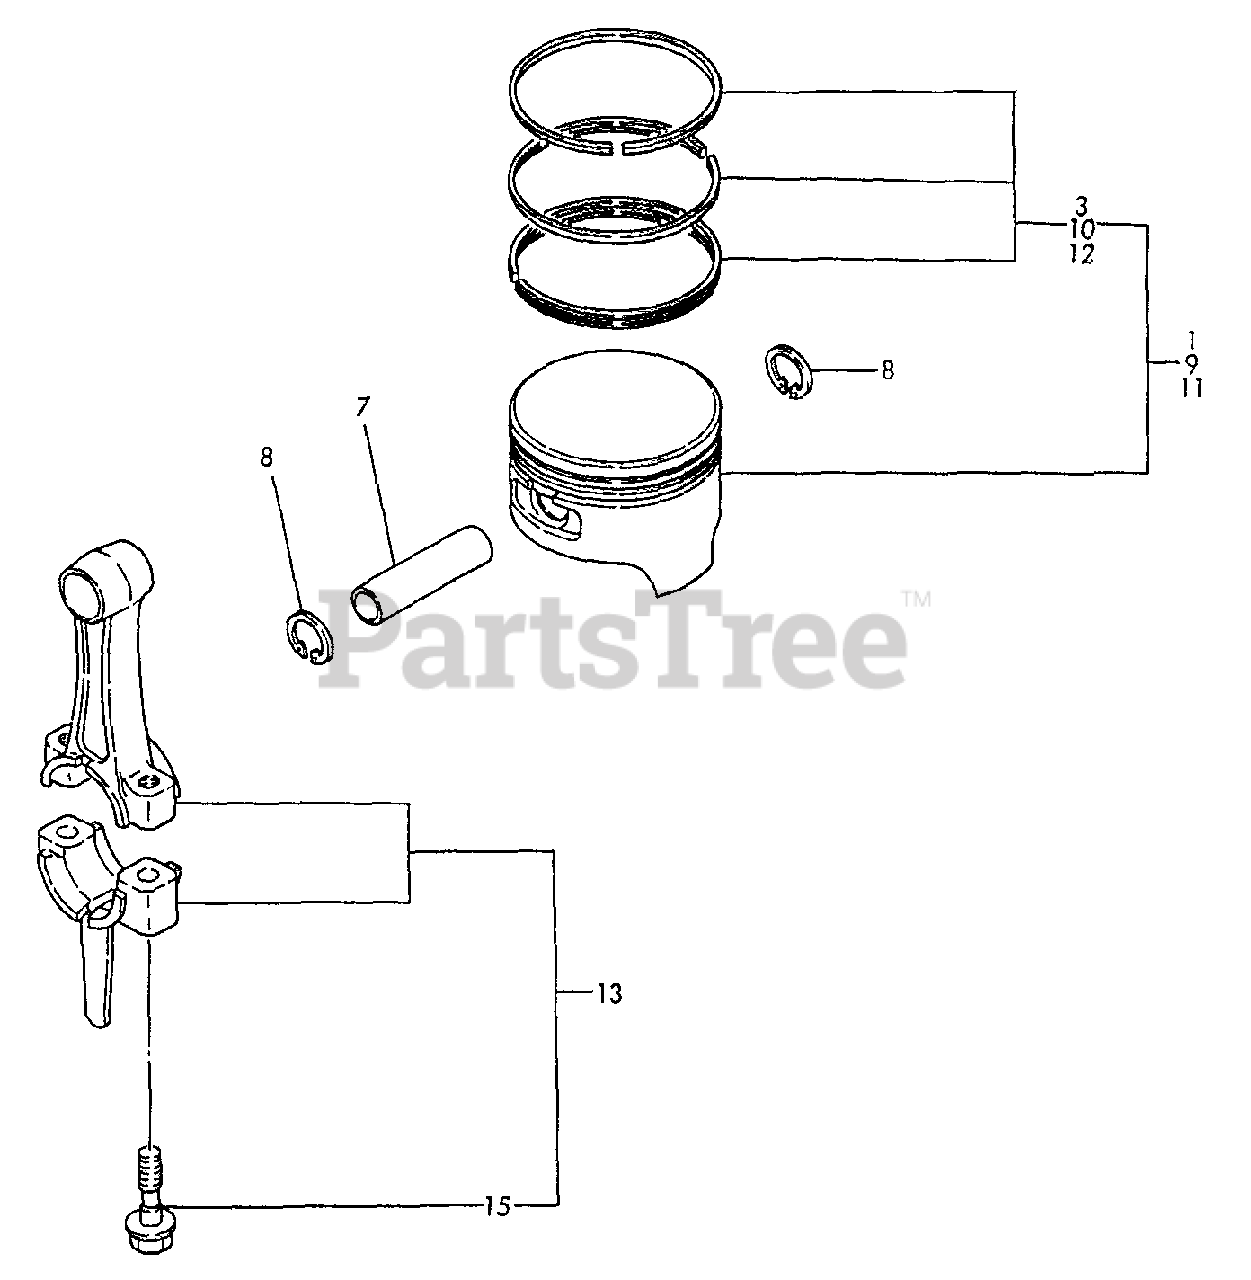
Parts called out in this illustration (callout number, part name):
1	PISTON ASSY
3	RING, PISTON
7	PIN, PISTON
8	RING, RETAINING - 16
9	PISTON ASSY O.S.=0.25
10	RING, PISTON
11	PISTON ASSY O.S.=0.5
12	RING, PISTON
13	CONNECTING ROD ASSY
15	BOLT, ROD
